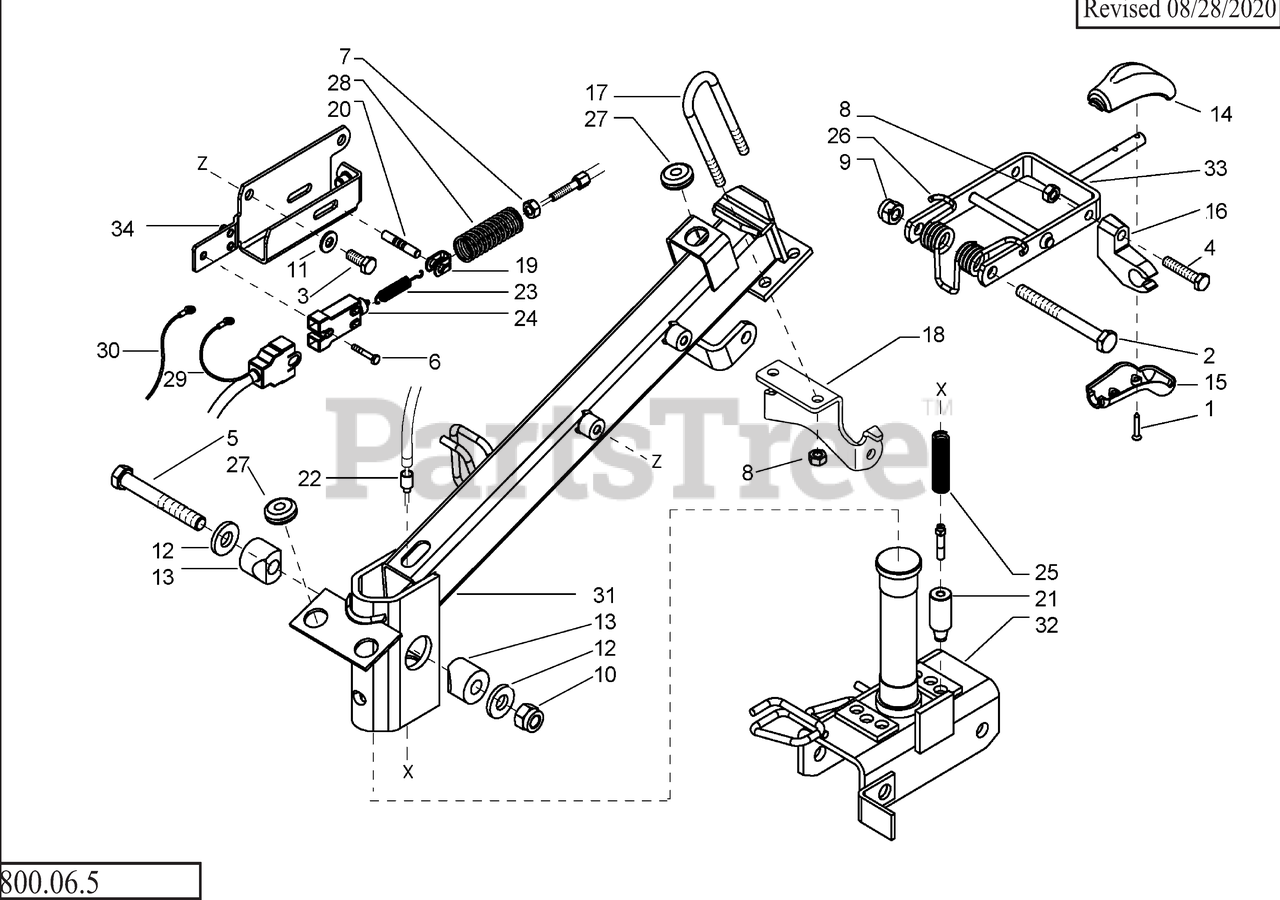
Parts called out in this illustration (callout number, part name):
1	SCREW, M5X25
2	CAP SCREW, M10X110 UNI 5737-8G
3	CAP SCREW, M8X20 UNI 5739-8G
4	CAP SCREW,
5	CAP SCREW, M12X80
6	CAP SCREW
7	NUT, M8
8	NUT, SELF LOCKING, M8
9	NUT, LOCK STANDARD, M10
10	NUT, LOCK DEFORMED, M12
11	WASHER, SUPER, M8
12	WASHER, SPRING
13	WEDGE
14	KNOB, UPPER HANDLE RELEASE
15	KNOB, LOWER HANDLE RELEASE
16	SUPPORT, CONTROL ROD
17	U-BOLT
18	BRACKET
19	MOTOR STOP FORK
20	M/S SPRING CHECK PIN
22	SHEATH END
23	SPRING
24	INTERLOCK SAFETY
25	SPRING, STEERING COLUMN
26	SPRING, HANDLEBAR RELEASE
27	SUPPORT, CAP
28	CHECK SPRING, MOTOR STOP
29	WIRE HARNESS, MOTOR STOP
30	GROUND WIRE
31	STEERING COLUMN
32	STEERING COUPLER
33	LEVER, HANDLE BAR
34	SUPPORT, ENGINE STOP
